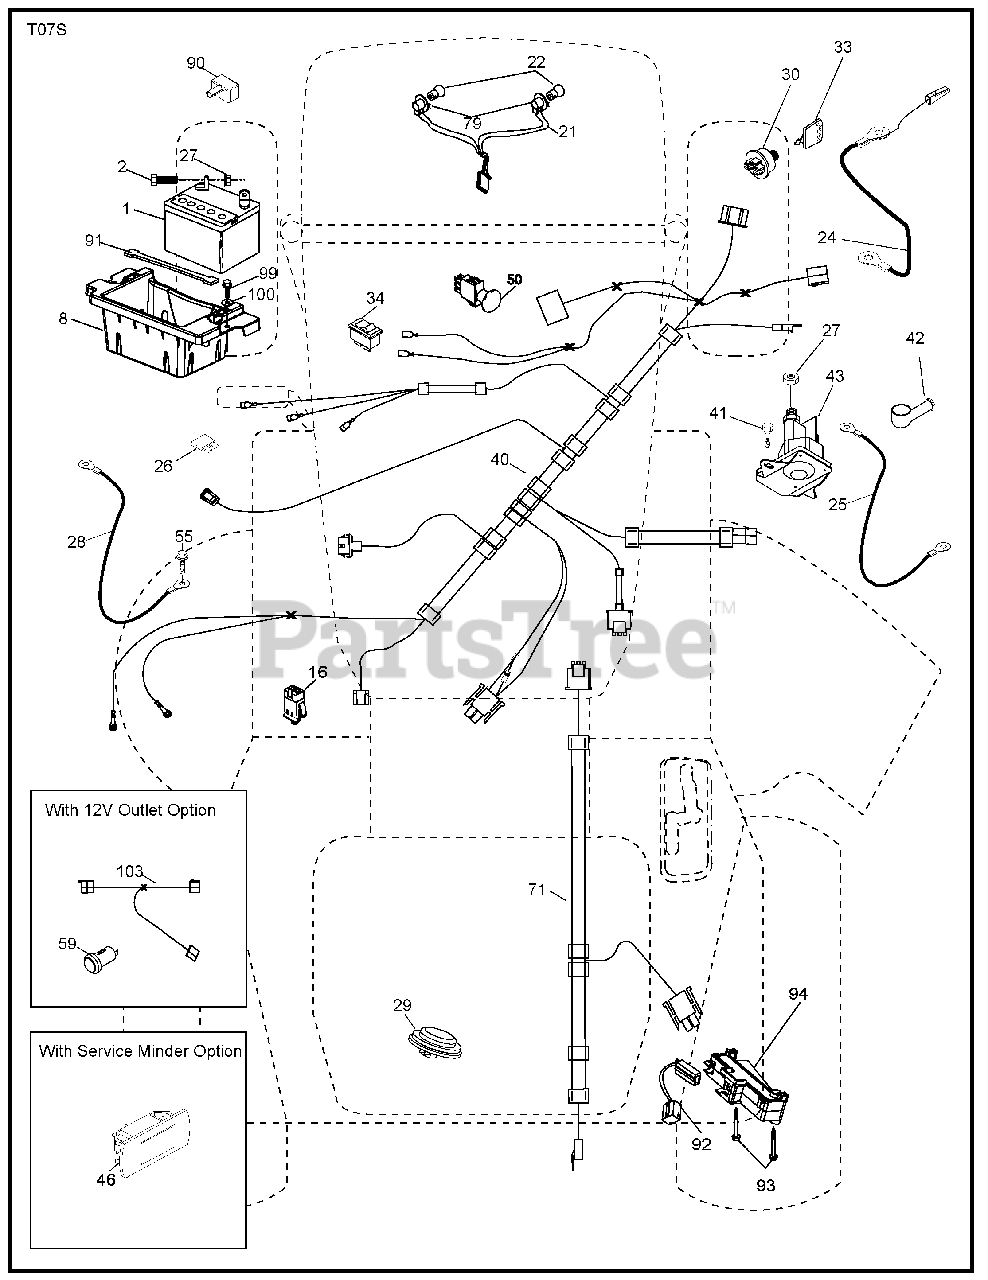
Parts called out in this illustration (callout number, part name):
1	Battery
2	Bolt Hex Head 1/4-20 x 3/4
8	Box Battery
16	Switch Interlock Push-In
21	Harness Socket Light W/4152J
22	Bulb Light
24	Cable Battery
25	Cable Start Red 17.5"
26	Fuse
27	Nut Keps Hex 1/4-20 unc
28	Cable, Ground
29	Switch, Seat
30	Switch, Ignition
33	Key/Chain
34	Switch Light / Reset
40	Harness Ign. Dash
41	Screw Thd Cut 1/4-20 x 1/2
42	Cover, Terminal
43	Solenoid
46	Gauge Hourmeter
50	Switch, PTO
55	Screw Thdrol 5/16-18 x 3/4 TYTT
71	Harness Ignition, Chassis
79	Bulbholder Asm. Incan Descent
90	Cover Terminal Battery
91	Strap Battery Mount Front
92	Harness Pigtail Consle ROS
93	Screw Plastite 10-14 x 2.0
94	Module Reverse ROS
99	Screw Hexwsh Thdrol 1/4-20 x 3/4
100	Washer 9/32 x 7/8 x 16 Ga.
